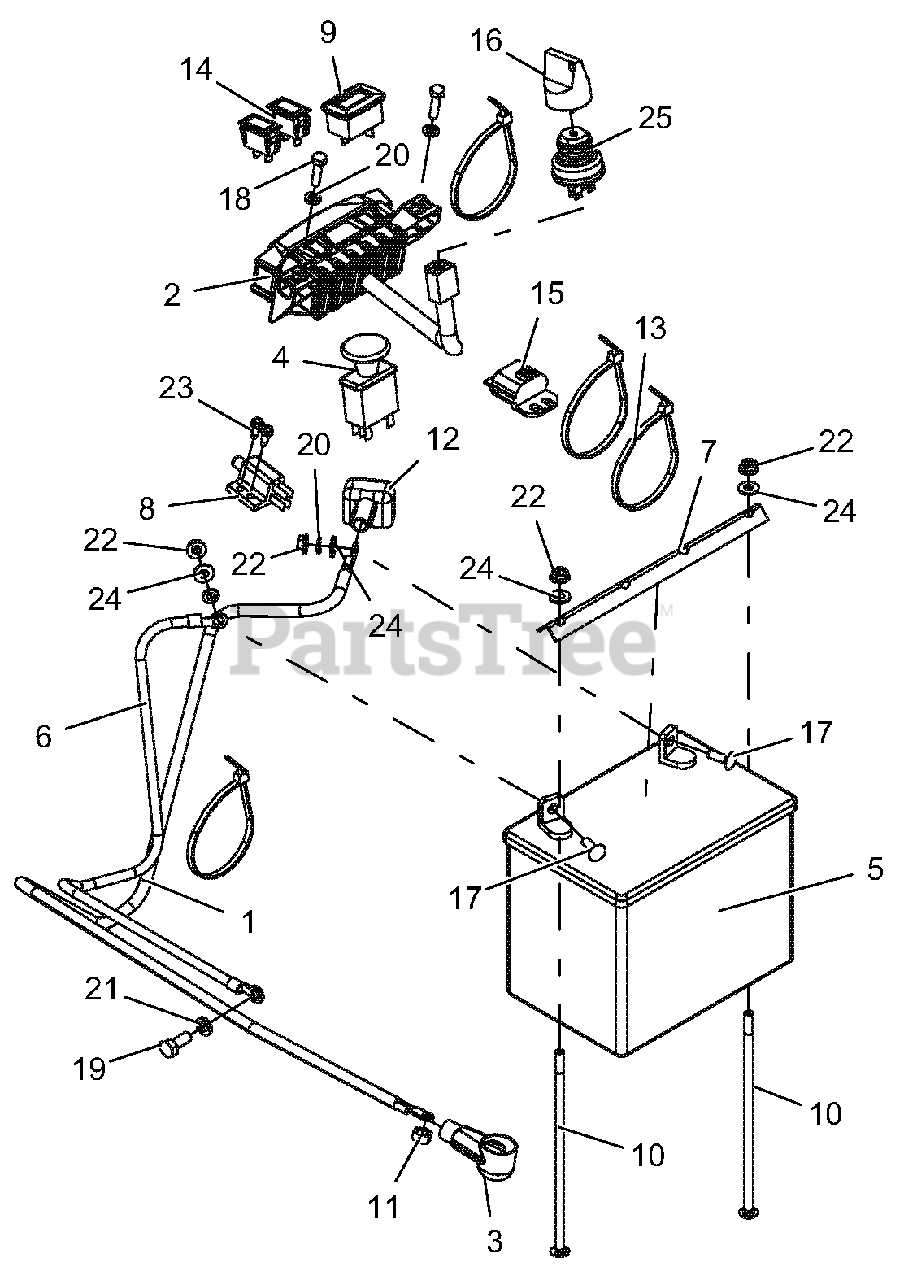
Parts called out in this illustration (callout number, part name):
1	CABLE, BATTERY - 42" POSITIVE
2	HARNESS, WIRE - HARNESS
3	BOOT, BATTERY TERMINAL - RED
4	SWITCH, CLUTCH
6	CABLE, NEGATIVE BATTERY 35.00"
7	HOLD DOWN - BLK
8	SWITCH- DOUBLE POLE N.O./N.O.
9	METER, HOUR W/MAINTENANCE
10	BLT-RDHDSQNK .250-20 x 7.50 GR2 YZ
11	NUT-LK-TOP M8-1.25 YWZC
12	INSULATOR
13	CABLE, TIE 5.50 LG
14	LIGHT, INDICATOR
15	MODULE, INTERLOCK
16	KEY, W/ COVER
17	BLT-RDHDSQNK .25-20 x .75 G5 YWZC
18	@BLT-HEX M6-1.0 x 25 YWZC
19	@BLT-HEX M8-1.25 x 20 YWZC
20	WSHR-LK .25 x .062 REG YWZC
21	WSHR-LK .31 x .078 REG YWZC
22	@NUT-SPNLK-FLG .25-20 YWZC
23	SCR-TAP 10-24 x .50 HWH TR YWZC
24	WSHR-FL-STL .281 x .62 x .065 YWZC
25	SWITCH, IGNITION
